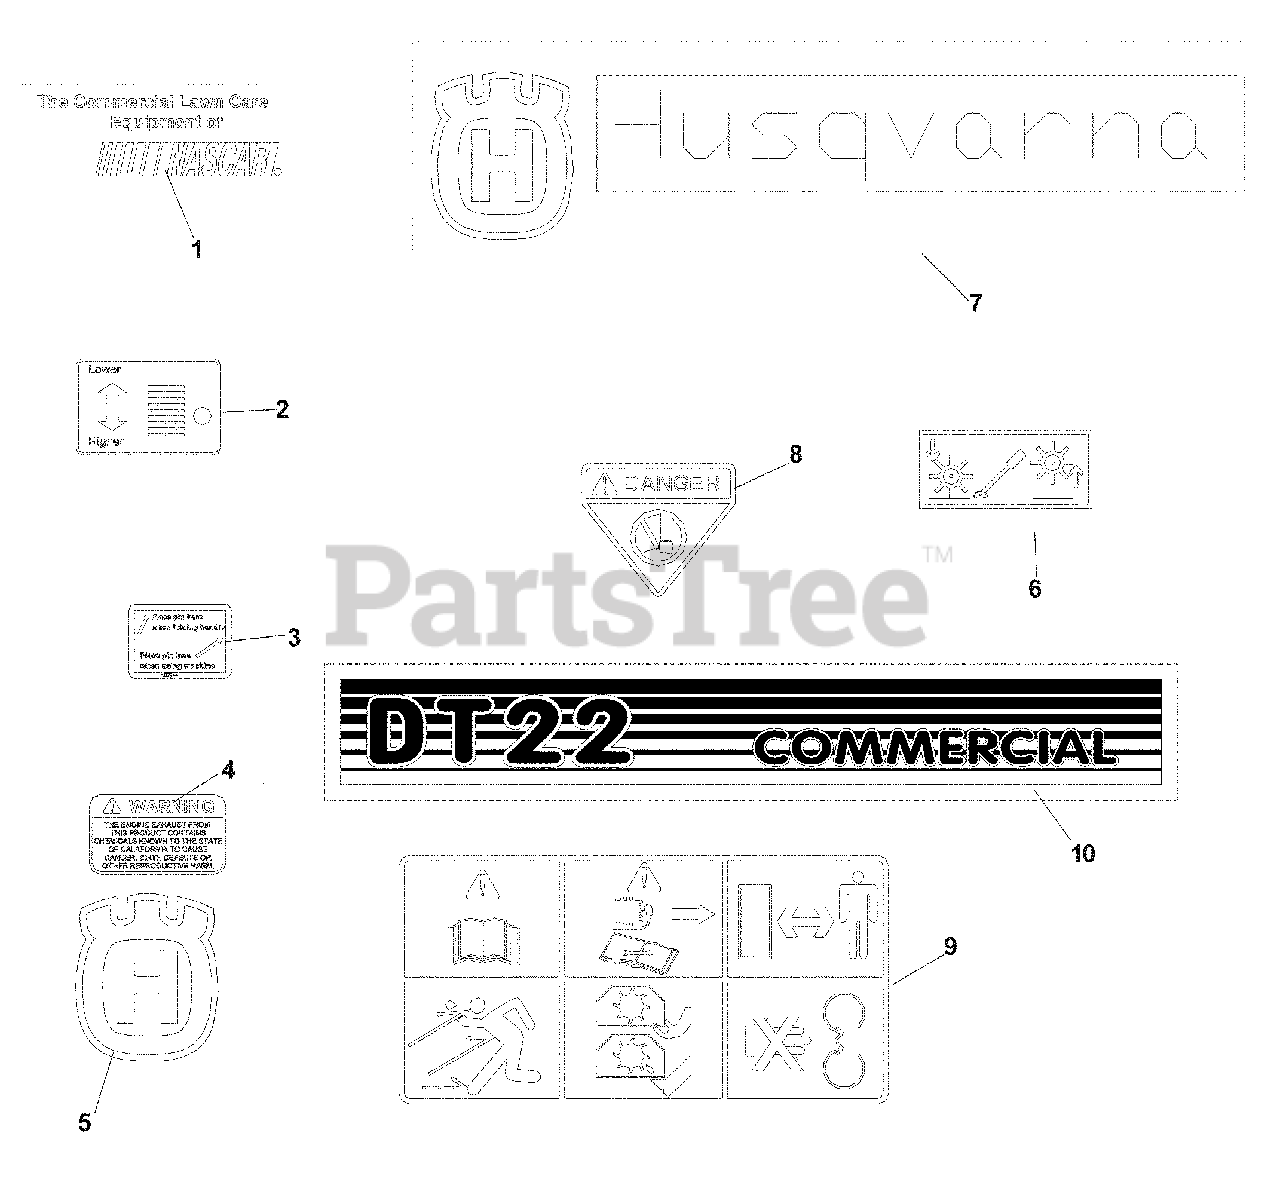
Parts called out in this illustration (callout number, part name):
1	DECAL, NASCAR
2	DECAL, HEIGHT
3	DECAL, HANDLE PIN
4	DECAL, PROP 65
5	DECAL SMALL CROWN
6	DECAL, HEIGHT ADJUST
7	DECAL, 12" HUSQVARNA W/CROWN
8	DECAL, FOOT DANGER
9	DECAL, GRAPHIC
10	DECAL, DT22
